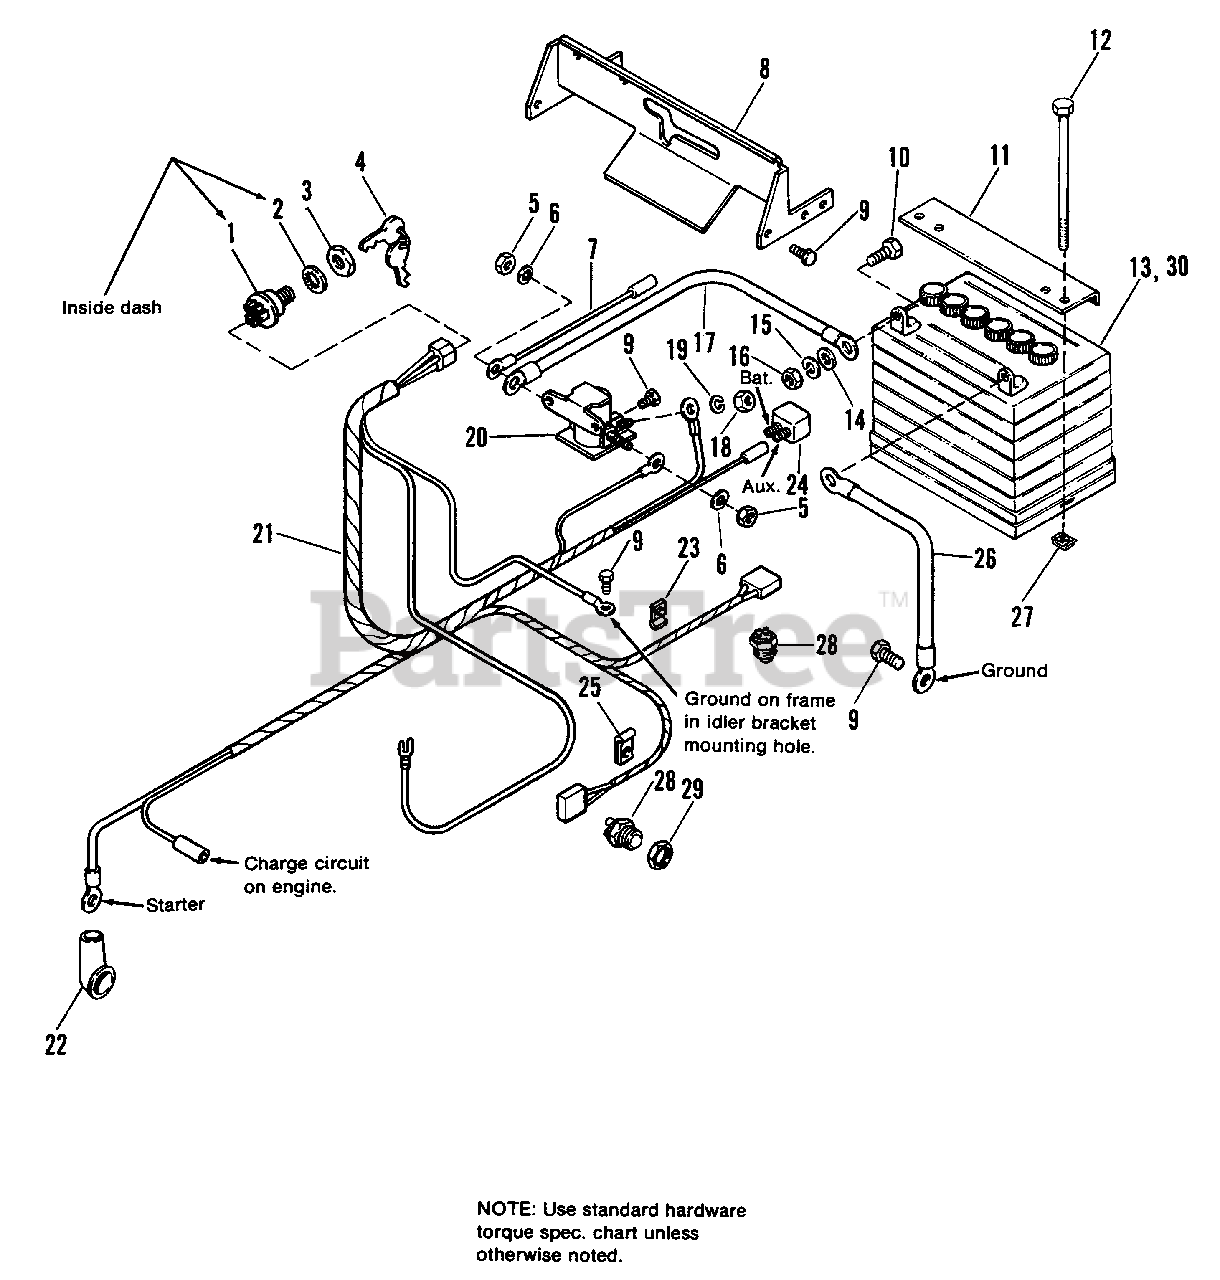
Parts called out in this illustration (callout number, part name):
1	SWITCH, Ignition
2	LOCKWASHER, Internal Tooth, 5/8
3	NUT, 5/8-32
5	NUT, Hex, 5/16-18
6	LOCKWASHER, 5/16
8	QUADRANT, Shift
9	SCREW, Taptite, 1/4-20 x 3/8
10	CAPSCREW, Hex, 1/4-20 x 3/4 (4208 Only)
11	CLAMP, Battery
12	CAPSCREW, Hex, 1/4-20 x 7-1/2
13	BATTERY SERVICE KIT, 32 Amp. (4208 Only)
14	WASHER, 1/4
15	LOCKWASHER, 1/4
16	NUT, Hex, 1/4-20
18	NUT, Hex, #10-32
19	LOCKWASHER, Ext., #10
21	HARNESS, Wiring
22	COVER, Terminal
23	CLIP, Speed
24	CIRCUIT BREAKER
27	NUT, Retainer, 1/4-20
28	SWITCH, Interlock
29	LOCKNUT, 9/16-18
30	BATTERY SERVICE KIT, 39 Amp. (4211 Only)
